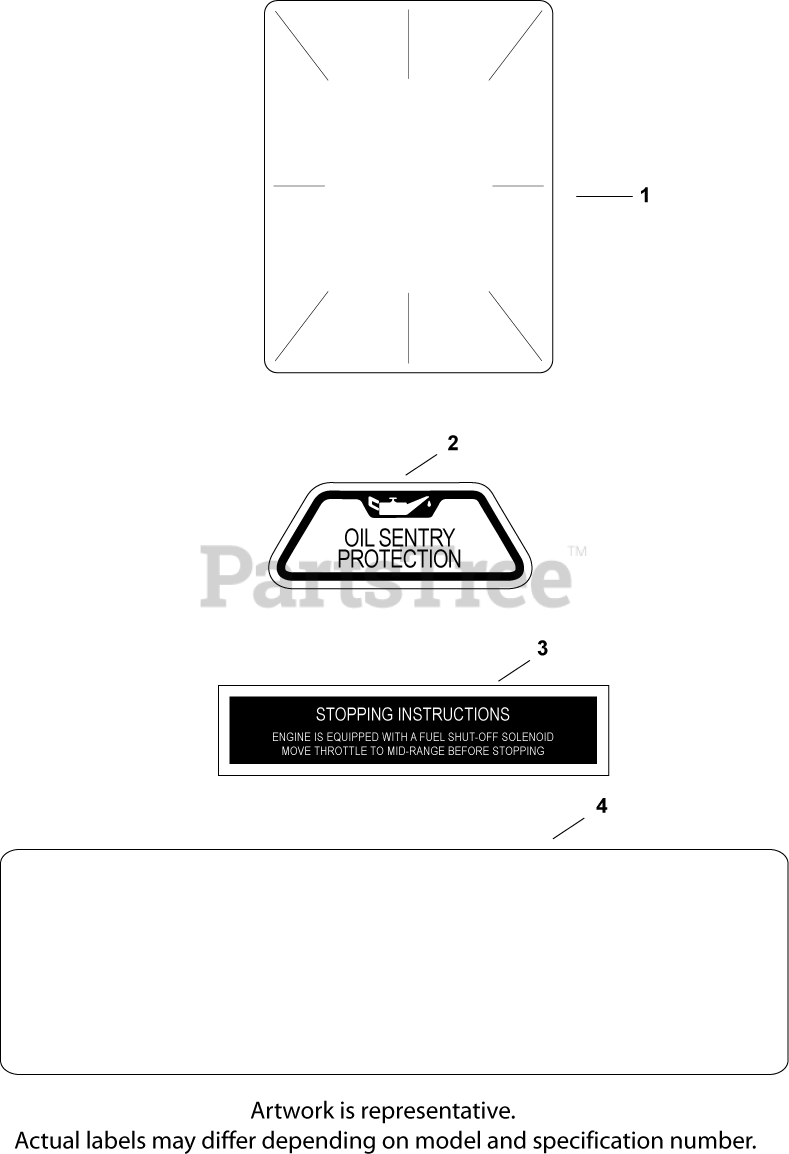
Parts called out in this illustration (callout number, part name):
1	DECAL, CLEAR LAMINATE USE 25 113 70-S
2	DECAL, OIL SENTRY - (#DSC)
3	DECAL, STOPPING INSTRUCTION
4	DECAL, 20 HP - DISCONTINUED
